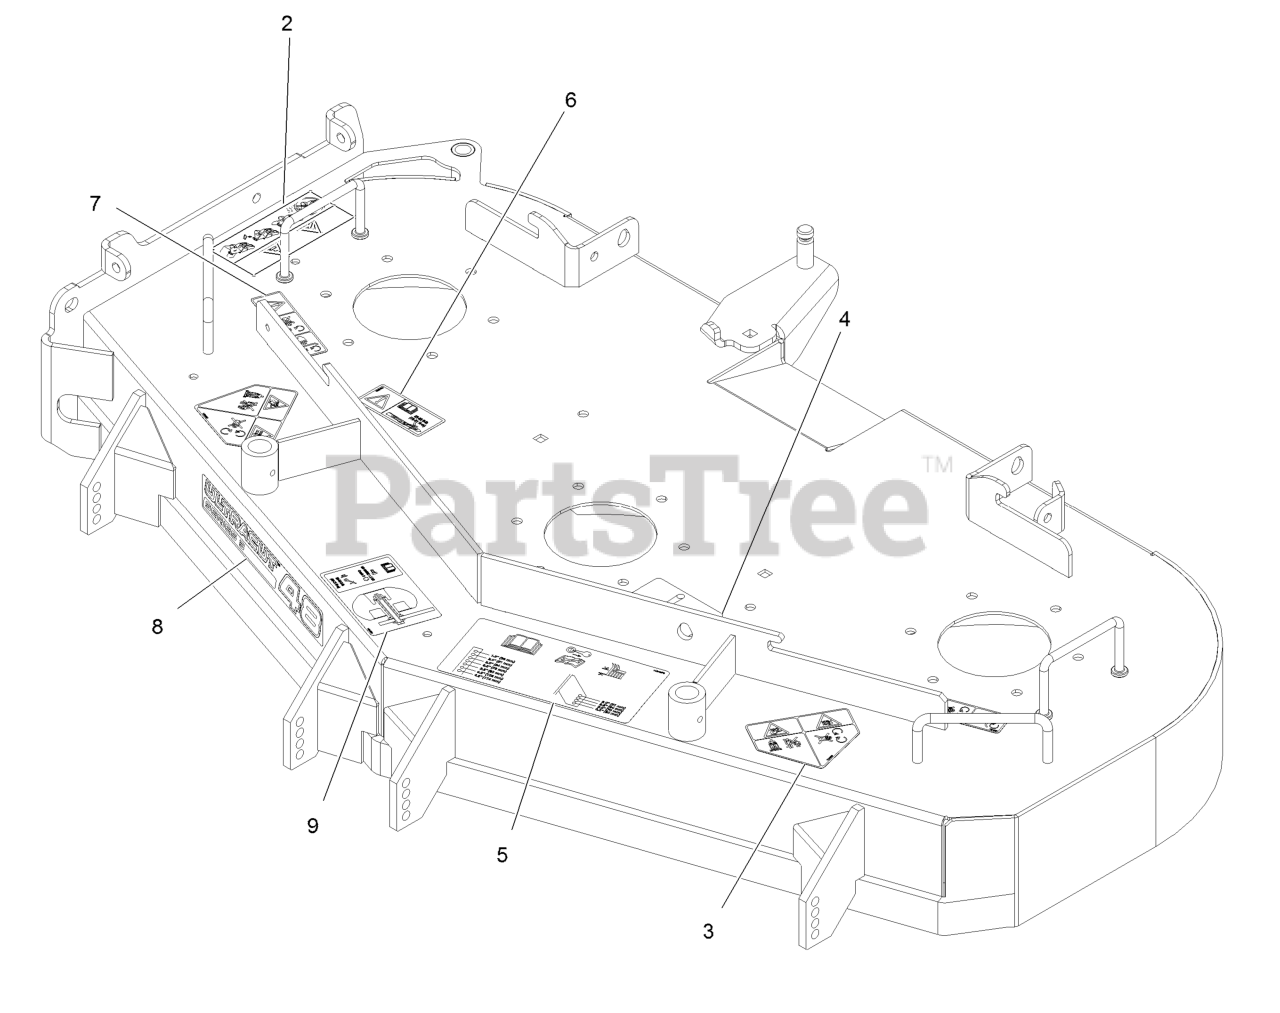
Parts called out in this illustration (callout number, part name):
2	Decal-Warning, Bagger
3	Decal-Danger
4	Decal-Belt Routing
5	Decal-Anti-Scalp
6	Decal-Bolt Torque
7	Decal-Cover, Missing
8	Decal-Ultracut 48 Series 3
9	Decal-Roller Mounting
